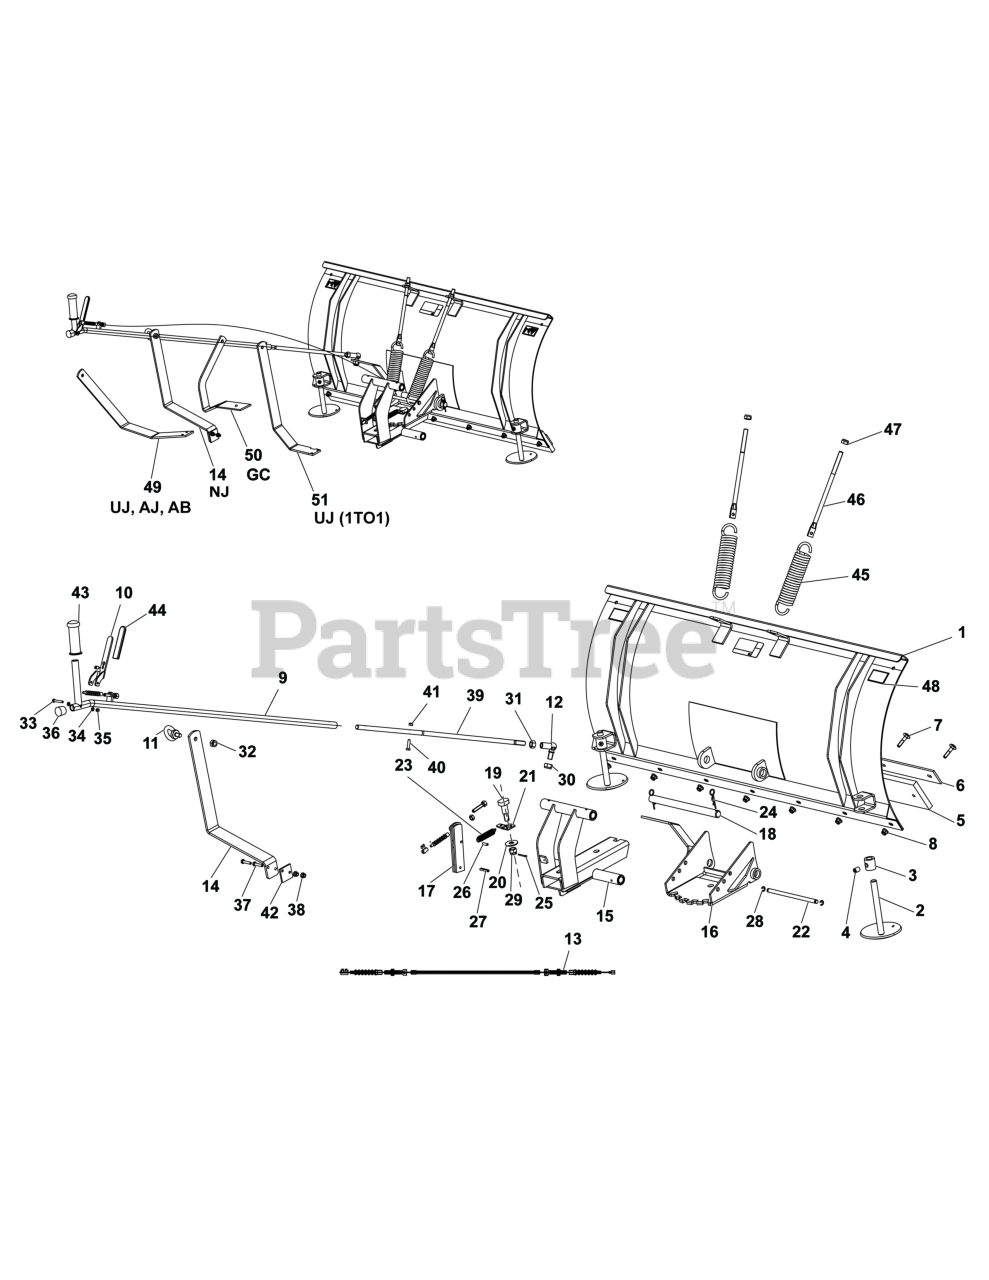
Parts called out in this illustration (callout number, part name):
1	BLADE, Dozer
12	JOINT, BALL
14	BRACKET
28	RING, Locking
49	BRACKET
50	BRACKET
51	BRACKET
